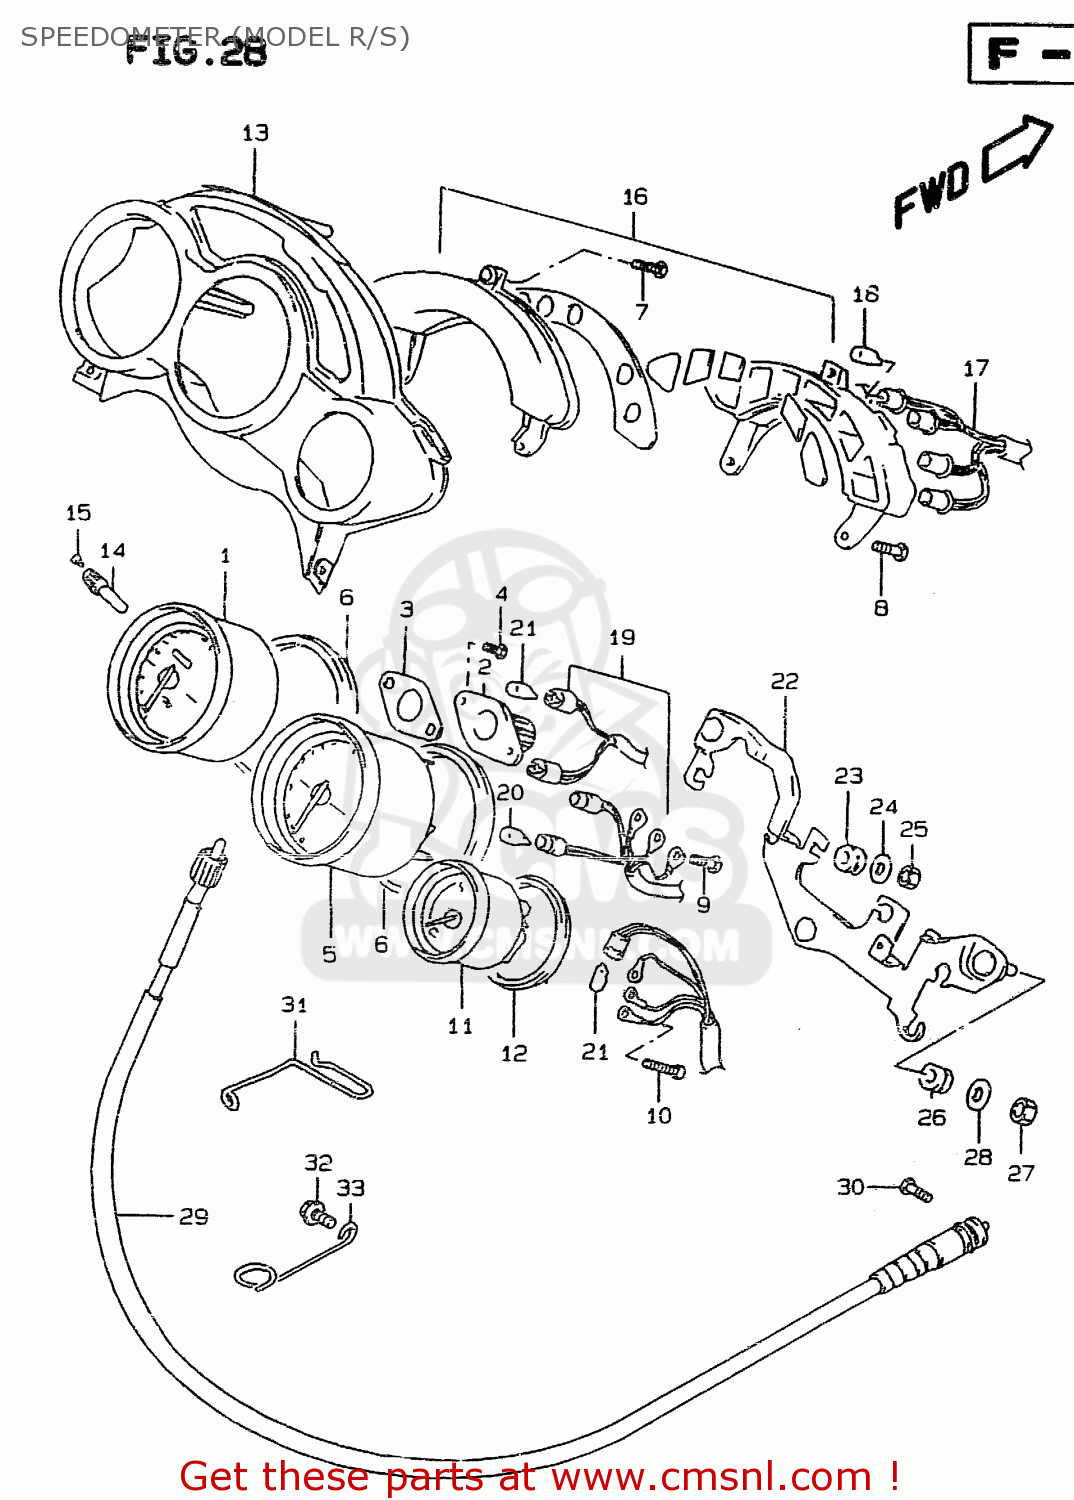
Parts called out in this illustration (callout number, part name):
1	SPEEDOMETER
2	GEAR BOX
3	GASKET,METER GEAR BOX (NAS)
4	SCREW
5	TACHOMETER
6	CUSHION,METER
7	SCREW
8	SCREW
9	SCREW
10	SCREW(3X22)
11	TEMP METER
12	CUSHION,TEMP METER
13	VISOR
14	KNOB,TRIP METER
15	SCREW(2X6)
16	BOX ASSY,PILOT
17	CORD ASSY,PILOT BOX
18	BULB(12V3.4W,T10,BF175-01450A)
19	CORD ASSEMBLY
20	BULB(12V1.7W,WB372,T7)
21	BULB(12V1.7W,T6.5)
22	BRACKET,METER
23	CUSHION,METER
24	WASHER,METER
25	NUT
26	CUSHION
27	SPACER (6.1X8X9.5)
28	NUT
29	CABLE ASSY,SPEEDOMETER
30	SCREW
31	GUIDE,SPEEDOMETER CABLE
32	BOLT
33	GUIDE,SPEEDOMETER CABLE NO.3
